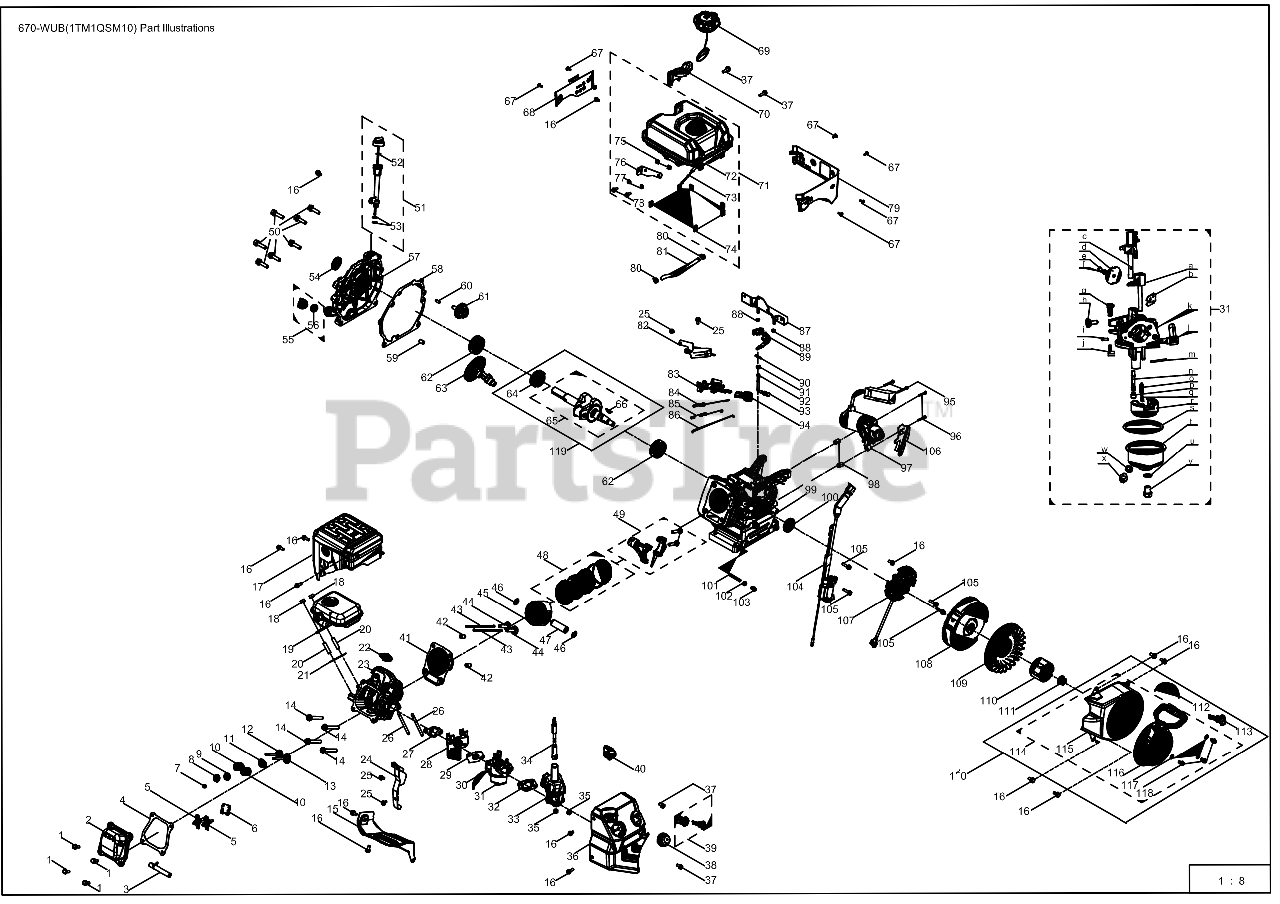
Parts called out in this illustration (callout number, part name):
1	BOLT M6 x 16
2	VALVE COVER
3	BREATHER HOSE
4	Gasket, Valve Cover
5	ROCKER ARM ASSEMBLY
6	ROCKER ARM BASE
7	EXHAUST VALVE ADJUSTER
8	EXHAUST VALVE SPRING RETAINER
9	INTAKE VALVE SPRING RETAINER
10	VALVE SPRING
11	INTAKE VALVE SEAL
12	EXHAUST VALVE
13	INTAKE VALVE
14	BOLT M8-1.25 x 55 GR10.9
15	AIR SHIELD
16	BOLT M6-1 x 12 GR8.8
17	MUFFLER GUARD
19	MUFFLER
20	STUD M8-1.25 x 34
21	MUFFLER GASKET
22	SPARK PLUG
23	CYLINDER HEAD
24	SNOW GUARD
25	BOLT M6-1 x 12 GR8.8
26	STUD M6 x 90
27	Gasket, Carburetor Insulator
28	INSULATOR
29	Gasket, Carburetor
30	PRIMER HOSE
31	CARBURETOR ASSEMBLY
32	Gasket, Air Filter
33	HEATER BOX
34	CHOKE LINKAGE
35	HEX NUT
36	CONTROL PANEL
37	BOLT M6-1 x 18 GR8.8
38	PRIMER
39	ENGINE KEY SWITCH ASSEMBLY
40	CHOKE LEVER
41	CYLINDER HEAD GASKET
42	DOWEL PIN
43	PUSH ROD
44	TAPPET
45	PISTON
46	PISTON PIN SNAP
47	PISTON PIN
48	PISTON RING SET
49	CONNECTING ROD
50	BOLT M8-1.25 x 32 GR5.8
51	DIPSTICK ASSEMBLY
52	DIPSTICK O-RING
53	OIL FILL TUBE O-RING
54	OIL SEAL
55	OIL PLUG
56	O-RING 15.8 x 2
57	CRANKCASE COVER
58	CRANKCASE COVER GASKET
59	DOWEL PIN
60	DOWEL PIN
61	GOVERNOR GEAR/SHAFT ASSEMBLY
62	BEARING
63	CAMSHAFT
64	DRIVE TIMING GEAR
65	CRANKSHAFT
66	FLYWHEEL KEY
67	BOLT: M5 x 14
68	DECORATIVE SHEET: RIGHT
69	FUEL CAP
70	DECORATIVE COVER
71	FUEL TANK
72	Fuel Tank
73	FUEL FILTER
74	FUEL TANK MOUNT THREADED TAB
76	FUEL TANK MOUNT TAB
77	WASHER 6.5 x 1.5 x 12
78	BOLT M6 x 20
79	DECORATIVE SHEET: LEFT
80	HOSE CLAMP
81	FUEL HOSE 6.3 x 12.5 x 162
82	GOVERNOR SHIELD
83	GOVERNOR GEAR BRACKET ASSEMBLY
84	GOVERNOR SPRING
85	THROTTLE SPRING
86	GOVERNOR ROD
87	FUEL TANK BRACKET
89	GOVERNOR LEVER
90	COTTER PIN
91	GOVERNOR SEAL
93	GOVERNOR SHAFT
94	THROTTLE KNOB
96	BOLT M6-1 x 32 GR8.8
97	ELECTRIC STARTER
98	DOWEL PIN
99	CRANKCASE
100	OIL SEAL
101	OIL DRAIN PIPE
102	WASHER
103	OIL DRAIN PLUG
104	IGNITION MODULE
105	BOLT M6-1 x 25 GR8.8
106	Lower Shield
107	Charging Coil
108	FLYWHEEL
109	COOLING FAN
110	STARTER CUP
111	FLYWHEEL NUT
112	CABLE TIE - 3 x 150
113	IGNITION KEY
114	RECOIL STARTER
115	BLOWER HOUSING
116	RECOIL STARTER ASSEMBLY
117	RECOIL FLAT WASHER
118	BOLT M6 x 10
119	Crankshaft
120	Recoil Starter
